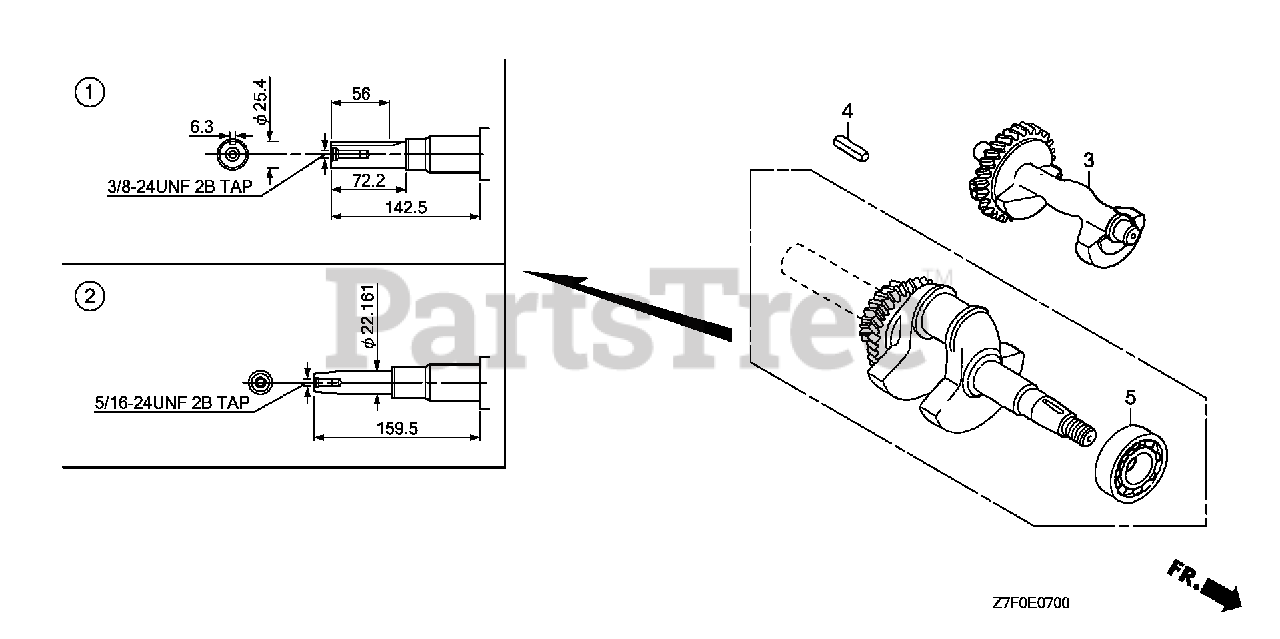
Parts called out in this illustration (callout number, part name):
2	CRANKSHAFT
3	WEIGHT, BALANCER
5	BEARING, RADIAL BALL (6207SH)
